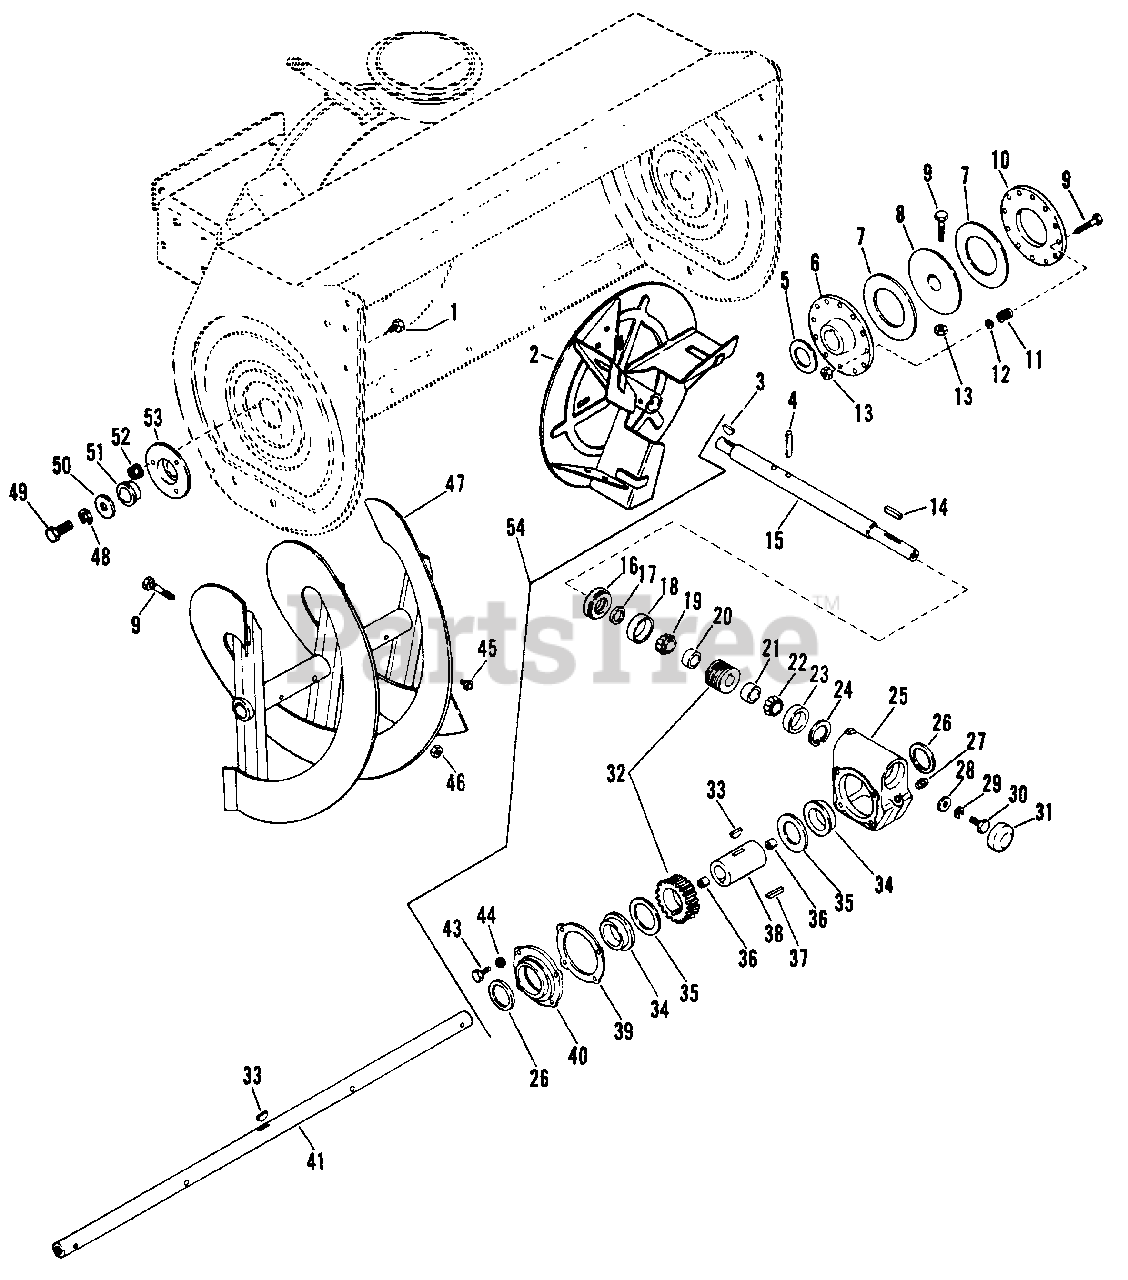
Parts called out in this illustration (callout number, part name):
1	Rib Neck Bolt 1/4-20x1/2
2	16" Fan
3	Key, Woodruff .187x.875 Hrd #11
4	Roll Pin 5/16x1-3/4
5	Washer 1.625/1.688x2.50x.060
6	Driver
7	Friction Disk
8	Driven Plate
9	Bolt, Hex 5/16-18x2.00
10	Pressure Plate
11	Spring, Comp. 3/4x2200 Rate
12	Washer .312/.343x.625x.062
13	Nut, Lock 5/16-18
14	Straight Key 3/16x1"x3/16
15	Worm Shaft
16	Adjustment Plug
17	Seal 1-1/8 I.D.
18	Bearing Cup 1-63/64 O.D.
19	Bearing Cone 1" I.D.
20	Bearing Spacer
21	Bearing Cone 3/4 I.D.
22	Cone, Bearing
23	Cup, Bearing
24	Snap Ring
25	Gear Case
26	Seal 1-5/8
27	Pipe Plug
28	Washer, Flat .344x.688x.065
29	Washer, Lock 5/16 SP
30	Bolt, Hex 5/16-18x.75
31	Dust Cap
32	Worm and Gear Set
33	Feather Key 1/4x7/8x1/4
34	Bushing, Flg. 1.62x1.87x11
35	Washer 1.623/1.627x2.500x.012
36	Sleeve Bushing 1-1/8x1-1/4x1"
37	Straight Key 1/4x1
38	Gear Case Shaft
39	Gasket
40	Gear Case Cover
41	40" Rake Shaft
43	Bolt, Hex 1/4-20x.875
44	Washer, Lock 1/4 Ext. Th TYA
45	Zerk Fitting
46	Two Way Lock Nut 5/16-18 Gr A
47	L.H. Auger w/Zerk
47	R.H. Auger w/Zerk
48	Washer, Lock 1/2 SP Heavy
49	Bolt, Hex 1/2-13x1.00
50	Washer .506/.516x1.441x.125
51	Flange Bushing 1"x1-1/8x5/8
52	Flange Whiz Lock Nut 1/4-20
53	Bearing Support
54	Gear Case Assembly
